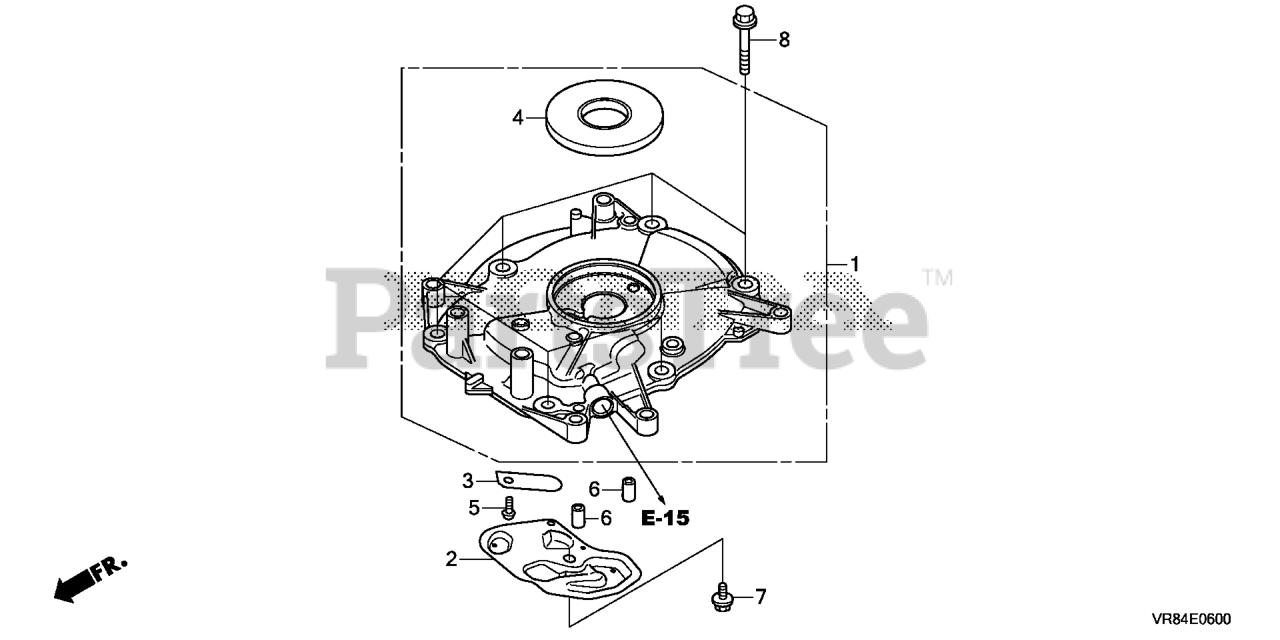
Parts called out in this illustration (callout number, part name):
1	COVER ASSY., CRANKCASE
2	COVER, BREATHER
3	PLATE, VALVE
4	OIL SEAL (25.4X62X6)
4	OIL SEAL (25.4X62X6) (FRG-NOK)
5	SCREW, PAN (5X8)
6	PIN A, DOWEL (8X14)
7	BOLT, FLANGE (6X14)
8	BOLT, FLANGE (8X25)
